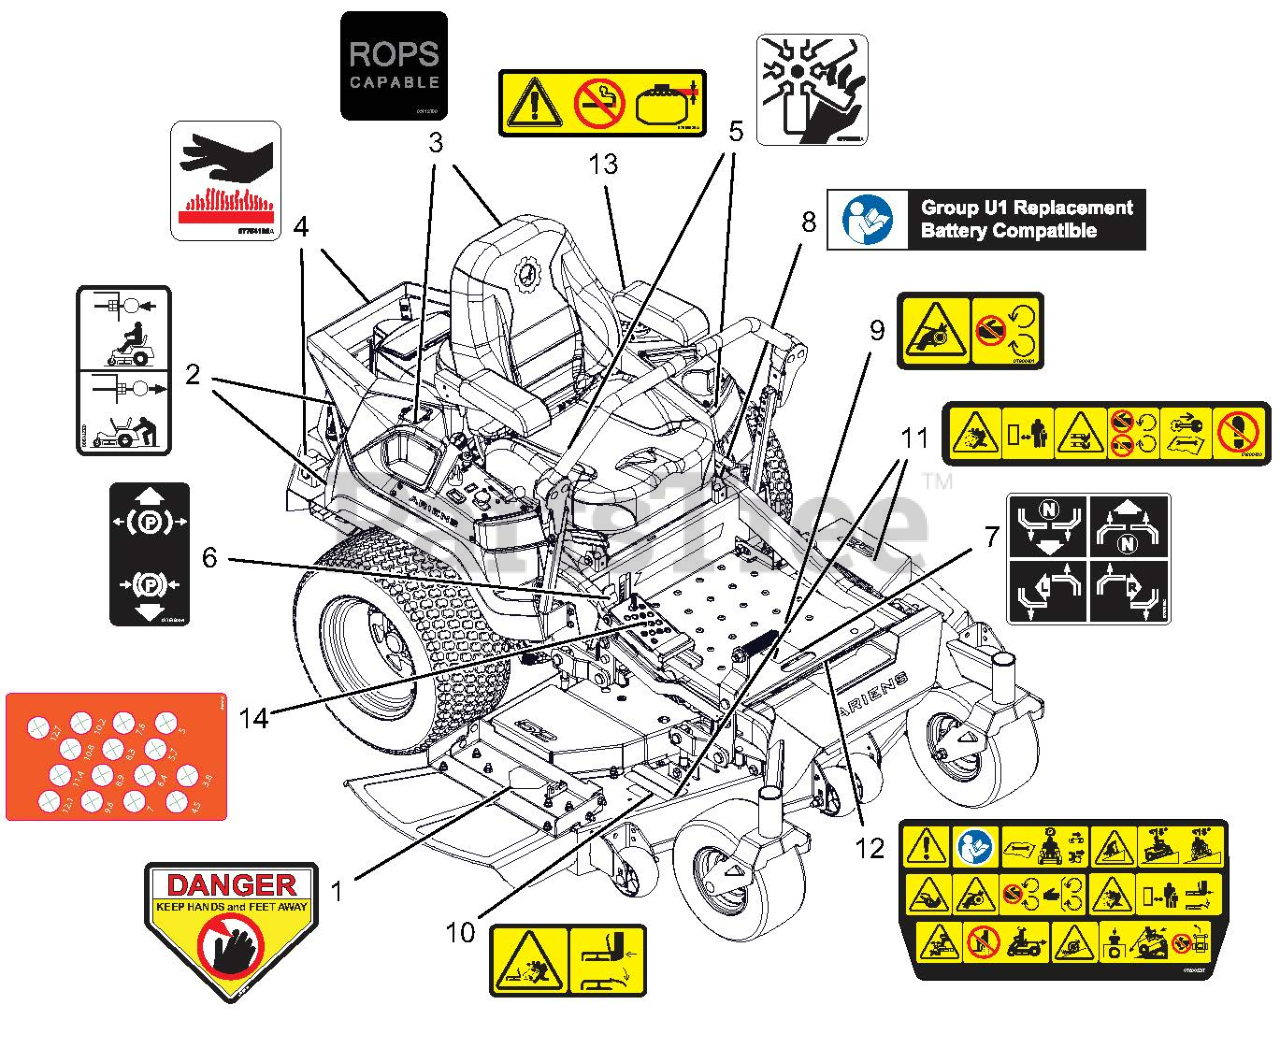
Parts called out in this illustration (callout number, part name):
1	DECAL, DANGER
2	DECAL, TRANSMISSION DISCONNECT
3	DECAL, ROPS LOCATION
4	DECAL, HOT SURFACE
5	DECAL, DANGER FAN
6	DECAL, PARKING BRAKE LEVER
7	DECAL, INSTRUCTIONAL-STEERING
8	DECAL, U1 BATTERY REPLACEMENT
9	DECAL, SAFETY - GUARDING
10	DECAL, SAFETY - DECK GUARDING
11	DECAL, DECK SAFETY
12	DECAL, MAIN SAFETY
13	DECAL, FUEL WARNING
14	DECAL, APEX HOC METRIC
